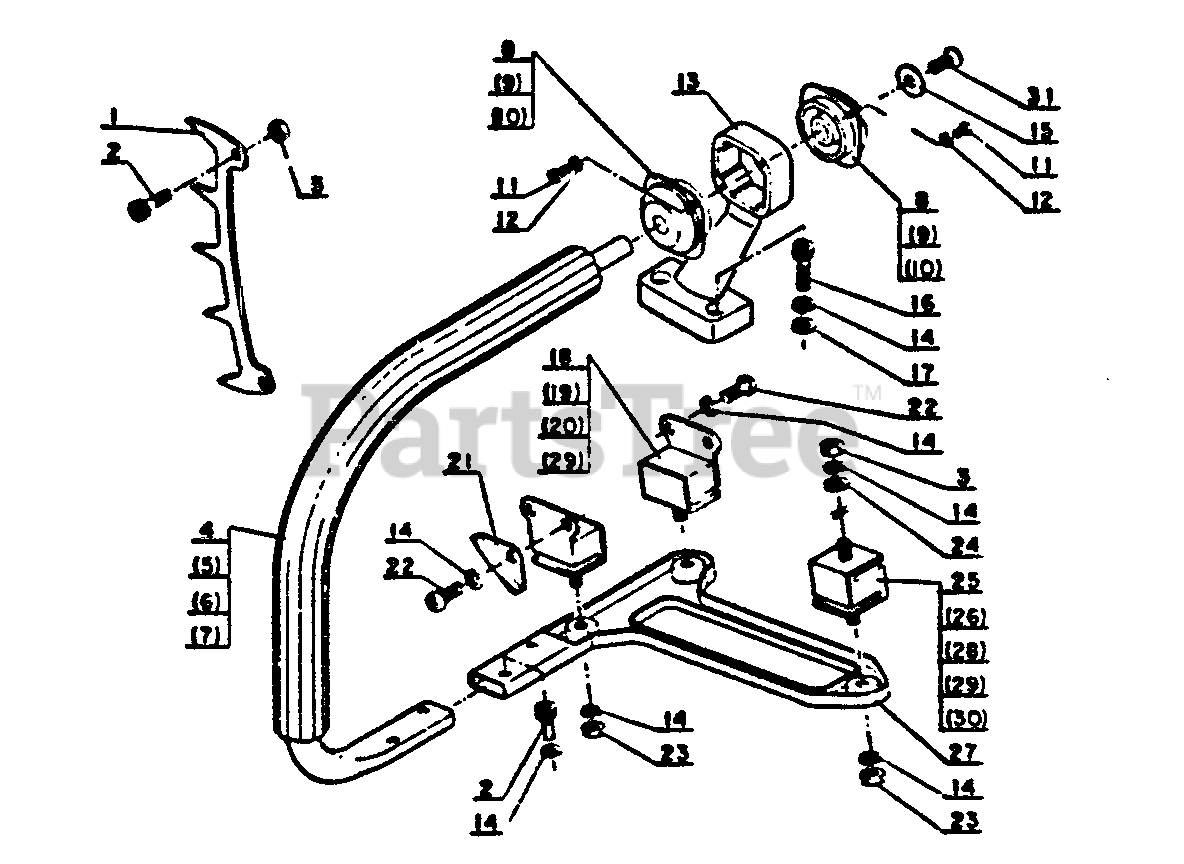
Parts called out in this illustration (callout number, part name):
1	BUMPER, SPIKED
2	BOLT - 5×12
3	LOCKNUT - 5
4	LEFT HANDLE
8	CUSHION RUBBER (L-U)
11	SCREW 3×8
12	LOCKWASHER - 3
13	BRACKET, HANDLE - UPPER
14	WASHER, SPRING 5
15	WASHER
16	BOLT - 5×18
17	WASHER
18	CUSHION RUBBER (L-L)
21	PLATE, WIND PROOF
22	SCREW - 5×12
23	NUT M5
24	WASHER, FLAT 5.5×10×0.8
25	CUSHION RUBBER (L-L: 2)
27	BRACKET, HANDLE - LOWER
31	SCREW 5×12
